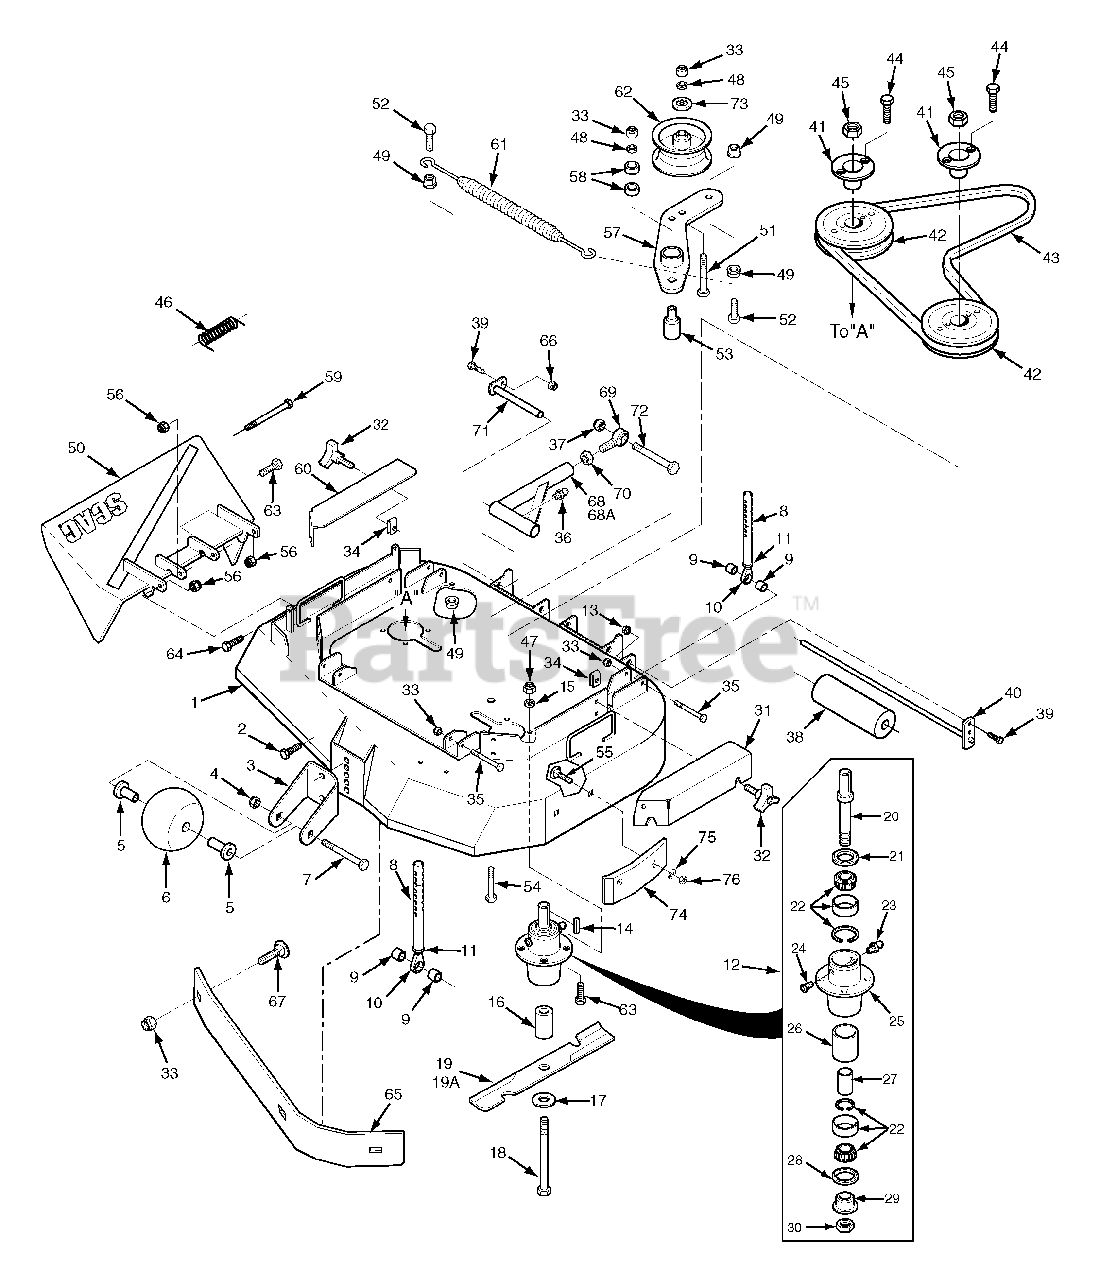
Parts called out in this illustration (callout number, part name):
1	Cutter Deck
2	Capscrew, 3/8-16 x 1.0" Serrated Flange Hex Hd
3	Bracket, Anti-Scalp Wheel
4	Lock Nut, 3/8-16 Center Lock
5	Bushing, .376" ID Oilite
6	Wheel, Anti-Scalp
7	Bolt, Carriage 3/8-16 x 4"
8	Pin Assy., Deck Adj.
9	Spacer, Deck Adjustment Pin
10	Rod End, Male 3/8-24 RH Thread
11	Nut, 3/8-24 Jam
12	Spindle Assembly
13	Nut, 5/16-18 Serrated Flange
14	Key,1/4" x 1/4" x 2"
15	Lock Washer 5/16"
16	Spacer, Spindle
17	Flatwasher, 5/8 W
18	Bolt, Hex Head 5/8-11 x 9-1/2"
19	Cutter Blade, 18"
19A	Cutter Blade, 18" Hi Lift
20	Spindle Shaft
21	Seal, Cutter Spindle Top
22	Tapered Bearing Set (Two Bearings W/Race)
23	Grease Fitting
24	Relief Fitting, Cutter Spindle
25	Spindle Housing
26	Spacer, Outside
27	Spacer, Inside
28	Seal, Cutter Spindle Bottom
29	Spindle Bushing
30	Nut, Spindle
31	Belt Cover, LH
32	Wing Nut, 3/8-16
33	Nut, 3/8-16 Elastic Stop
34	U-Nut, 3/8-16
35	Bolt, Hex Head 3/8-16 x 2-1/2"
36	Grease Fitting, 90 Degree
37	Nut, 1/2-13 Elastic Stop
38	Guide, Roller
39	Bolt, Hex Head 5/16-18 x 1"
40	Roller Shaft
41	Tapered Hub
42	Pulley
43	Belt, Cutter Deck
44	Bolt, Hex Head 1/4-20 x 1" Gr. 8
45	Hex Nut, 5/8-11
46	Spring, Chute Return
47	Lock Nut, 5/16-18 Elastic Stop Grade 8
48	Flatwasher, 3/8" (.938 x .391 x .105)
49	Nut, 3/8-16 Serrated Flange
50	Discharge Chute
51	Capscrew, Hex Head 3/8-16 x 3"
52	Capscrew, Hex Head 3/8-16 x 1-1/2"
53	Pivot, Idler
54	Capscrew, Hex Head 38/16 x 3-1/4"
55	Bolt, Carriage 5/16-18 x 3/4"
56	Nut, 5/16-18 Elastic Stop
57	Idler Arm Weldment
58	Ball Bearing
59	Bolt, Hex Head 5/16-18 x 4-3/4"
60	Belt Cover, RH
61	Spring, Deck Idler
62	Pulley, Idler
63	Bolt, Hex Head 5/16-18 x 1-1/2" Grade 8
64	Bolt, Hex Head 5/16-18 x 1-3/4"
65	Baffle Weldment
66	Nut, 5/16-18 Serrated Flange
67	Bolt, Carriage 3/8-16 x 1"
68	Push Arm - LH
68A	Push Arm - RH
69	Rod End, Male 1/2-20 RH Thread
70	Nut, 1/2-20 Jam
71	Push Arm Shaft
72	Bolt, Hex Head 1/2-13 x 3"
73	Dust Shield
74	Pad, Deck Wear
75	Flatwasher, 5/16"
76	Hex Nut, 5/16-18 Center Locknut
